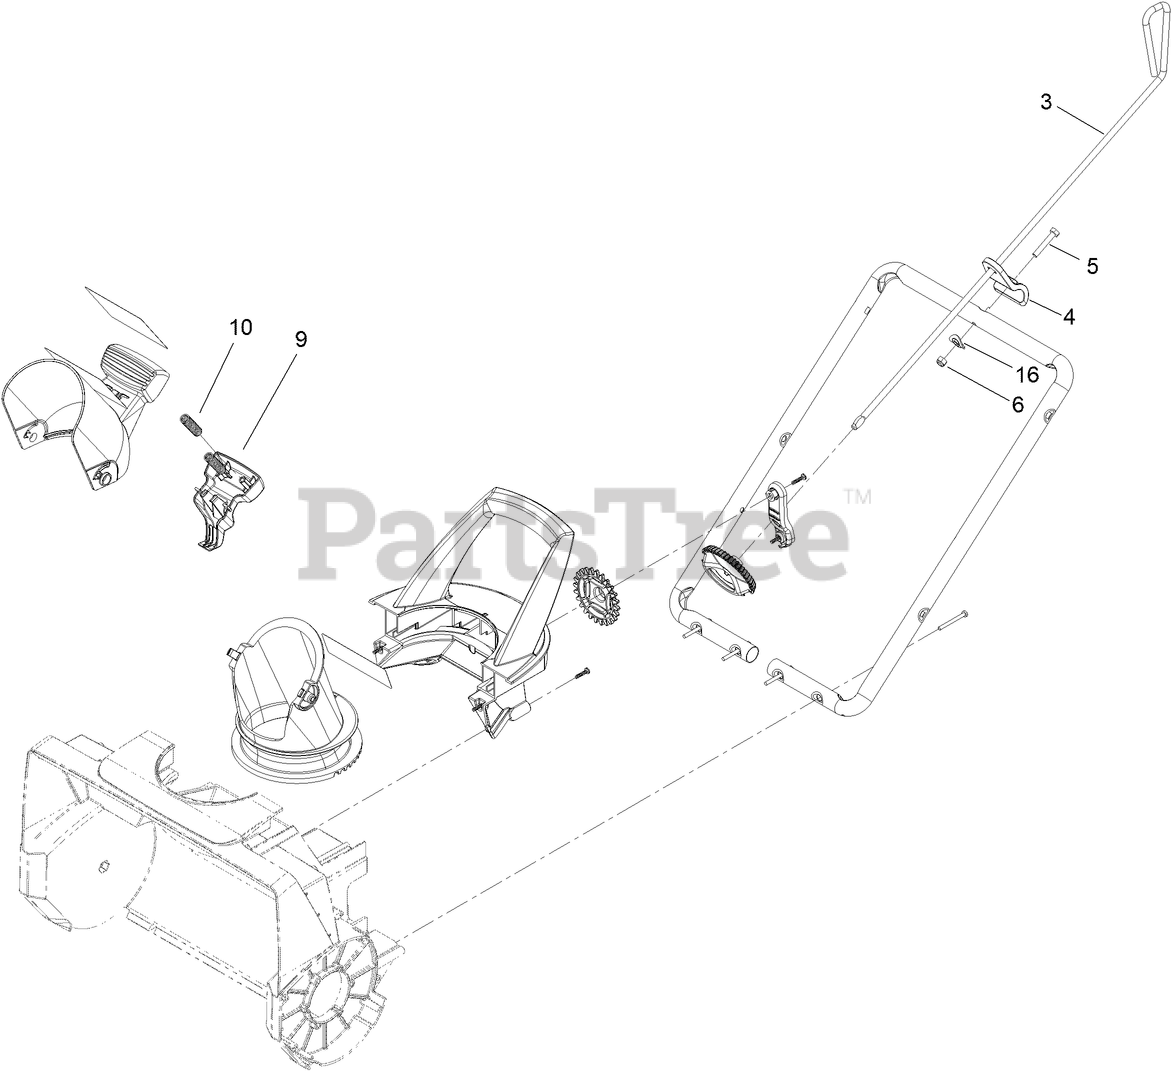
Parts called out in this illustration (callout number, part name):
3	ROD-CONTROL, CHUTE
4	GUIDE-ROD, CHUTE
6	SCREW-HH TAP
9	TRIGGER-DEFLECTOR
10	SPRING-COMPRESSION
16	WASHER-CUP
